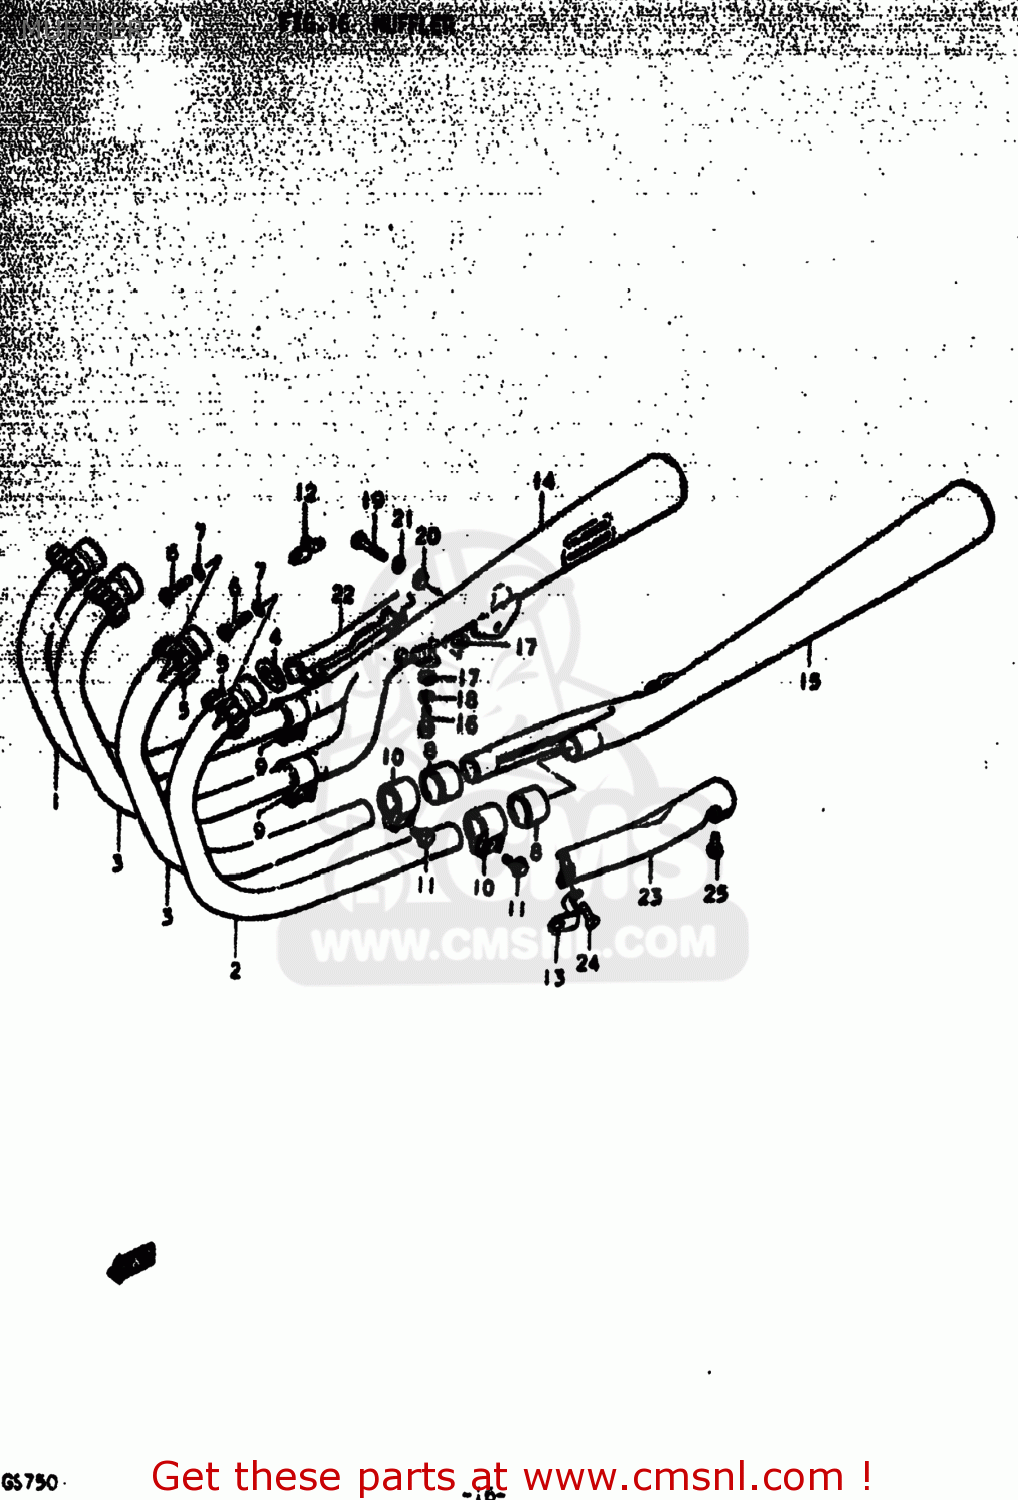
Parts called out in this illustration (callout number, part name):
1	PIPE,EXHAUST,RIGHT
2	PIPE,EXHAUST,LEFT
3	PIPE,EXHAUST CTR
4	GASKET,EXHAUST PIPE (NAS)
5	CLAMP,EXHAUST PIPE
6	BOLT
7	LOCK WASHER
8	CONNECTOR,MUFFLER
9	CLAMP
10	CLAMP
11	BOLT
12	PLATE, CONNECTOR RH
13	PLATE, CONNECTOR LH
14	BODY,MUFFLER
15	BODY,MUFFLER
16	BOLT
17	WASHER (8.2X20X1.6)
18	LOCK WASHER
19	BOLT 10X30
20	WASHER
21	LOCK WASHER
22	COVER,MUFFLER
23	COVER,MUFFLER
24	SCREW 5X20
25	SCREW
